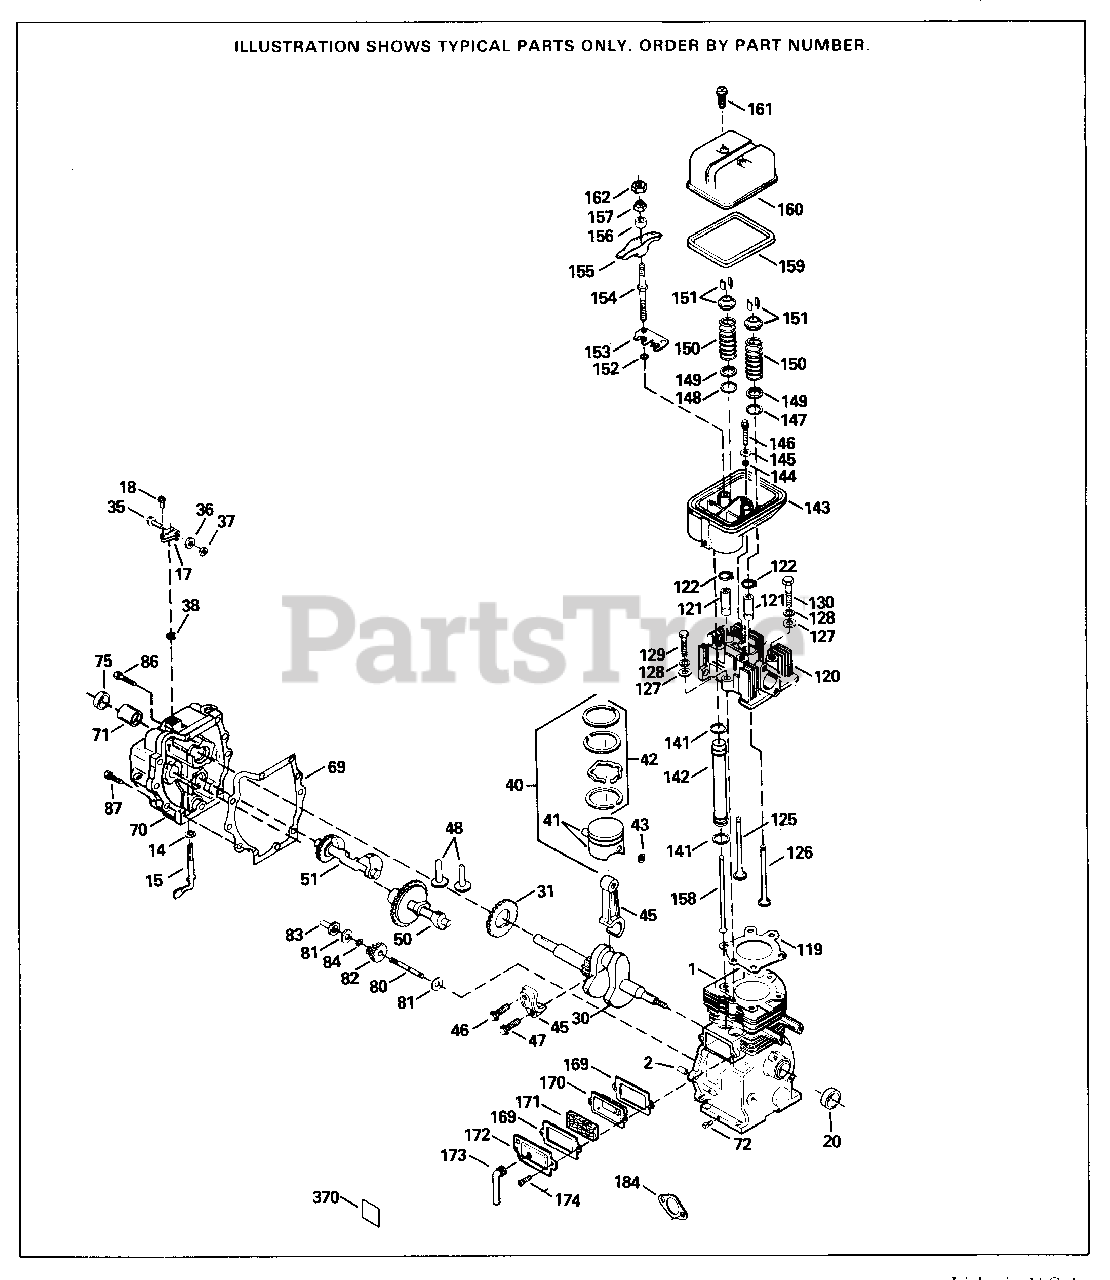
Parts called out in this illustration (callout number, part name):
1	"Cylinder (Incl. 2, 20, 72 & 80)/16")
2	Dowel Pin
14	Flat Washer
15	Governor Rod (Incl. 14 & 38)
17	Clamp, Throttle lever
18	Screw, 8-32 x 5/16"
20	Oil Seal
30	Crankshaft (Counterbalance)
31	Counterbalance Gear
35	Screw, 10-32 x 3/4"
36	Lock Washer #8
37	Lock Nut, 10-32
38	Retaining Ring
40	Piston, Pin & Ring Set (Std.)")
40	Piston, Pin & Ring Set (.010" OS)
40	Piston, Pin & Ring Set (.020" OS)
41	Piston & Pin Ass'y. (Std.) (Incl. 43)
41	Piston & Pin Ass'y. (.010" OS) Incl. 43
41	Piston & Pin Ass'y. (.020" OS) Incl. 43
42	Ring Set (Std.) (3-5/16")
42	Ring Set (.010" OS)
42	Ring Set (.020" OS)
43	Piston Pin Retaining Ring
45	Connecting Rod Ass'y. (Incl.46,47,49)
46	Bolt, Connecting rod
47	Bolt, Connecting rod
48	Valve Lifter
50	Camshaft (MCR)
51	Weight Assy., Counterbalance
69	Cylinder Cover Gasket
70	Cylinder Cover (Incl. 14, 15, 38, 71 & 75) & 75)
71	Crankshaft Bushing
72	Oil Drain Plug (Sq. hd., 1/4-18)
75	Oil Seal
80	Governor Shaft
81	WASHER
82	Governor Gear Assembly
83	Governor Spool
84	Retaining Ring
86	Screw, 1/4-20 x 1-3/16"
87	Screw, 1/4-20 x 1-11/16"
141	"O" Ring
144	"O" Ring
147	"O" Ring (Intake)
148	"O" Ring (Exhaust)
152	"O" Ring
157	Nut Assy., Lock (Incl. 162)
159	* "O" Ring Assy. (Incl. 2 of 161)
161	Screw, Torx T-20, 8-32 x 1/2"
162	Nut, Hex jam
169	Valve Cover Gasket
184	Gasket, Carburetor to intake pipe
370	Decal, Instruction
